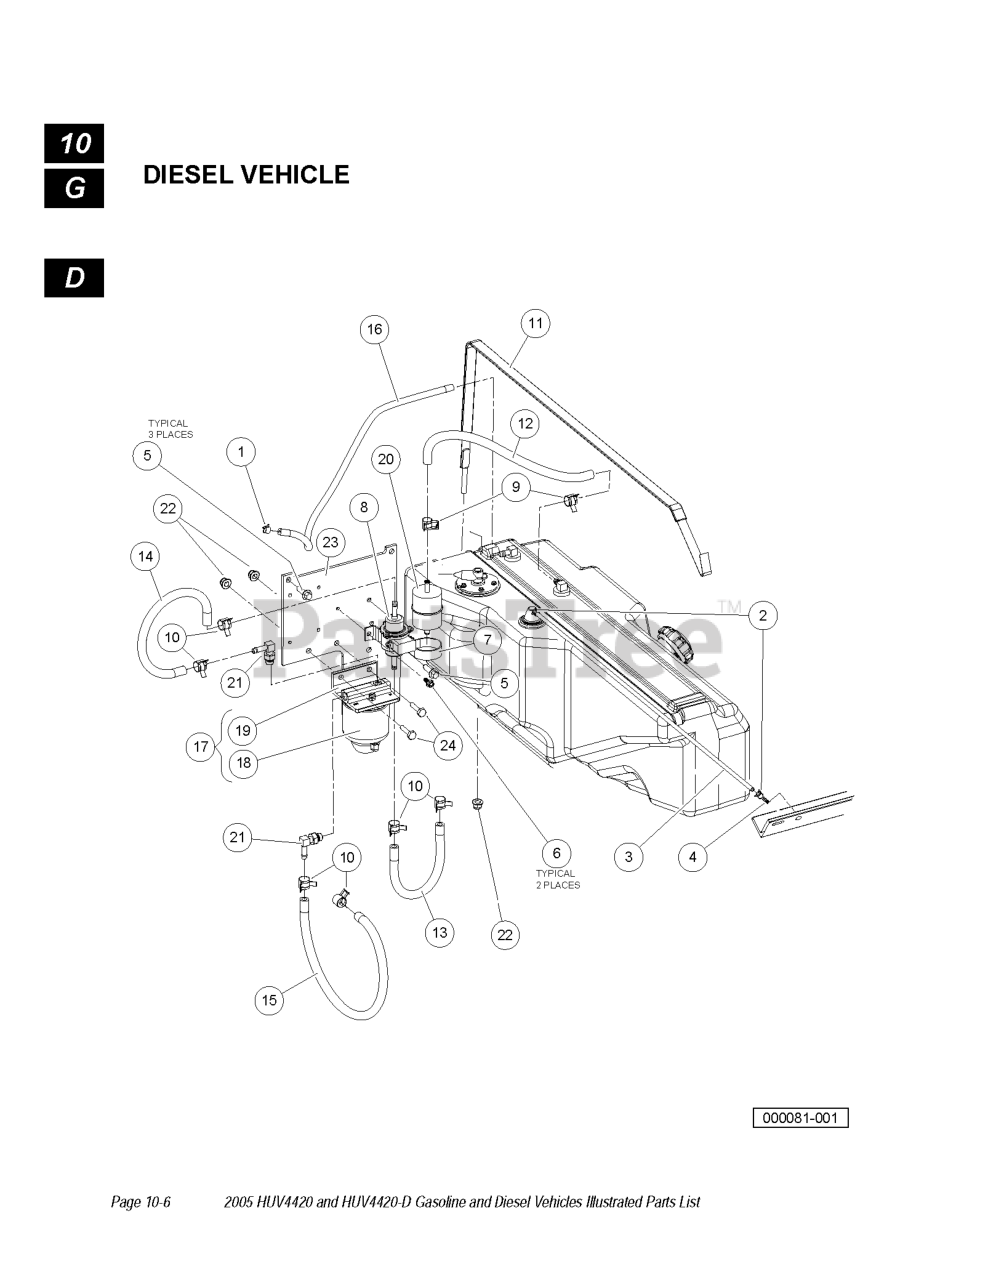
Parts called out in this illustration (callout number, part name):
1	CLAMP, GREEN HOSE
3	TUBE, CARBURETOR AIR VENT
5	SCREW-M8 X 1.25 30, TRI, HX F
6	SCREW, M6 X 16 TT HX FL HD
7	P-CLAMP, INSULATED 1.75 IN
8	PUMP, DIESEL FUEL ELECTRIC
9	CLAMP, HOSE, CTB 13MM
10	CLAMP, HOSE, CTB 14MM
11	STRAP, TANK, FUEL
12	HOSE, TANK TO PREFILTER DIESEL
13	HOSE, FUEL PREFILTER TO PUMP
14	HOSE, FUEL PUMP TO FILTER
15	HOSE, FUEL FILTER TO ENG
16	HOSE, FUEL RETURN
17	FILTER ASSY, FUEL
18	FILTER,FUEL
19	ADAPTER, 90-5 ORB, 5/16 TUBE
20	LOCK NUT, FLG M8 X 1.25 NYLON
21	PLATE, FUEL/OIL SYSTEM
22	BOLT, M8 X 1.25 X 30
